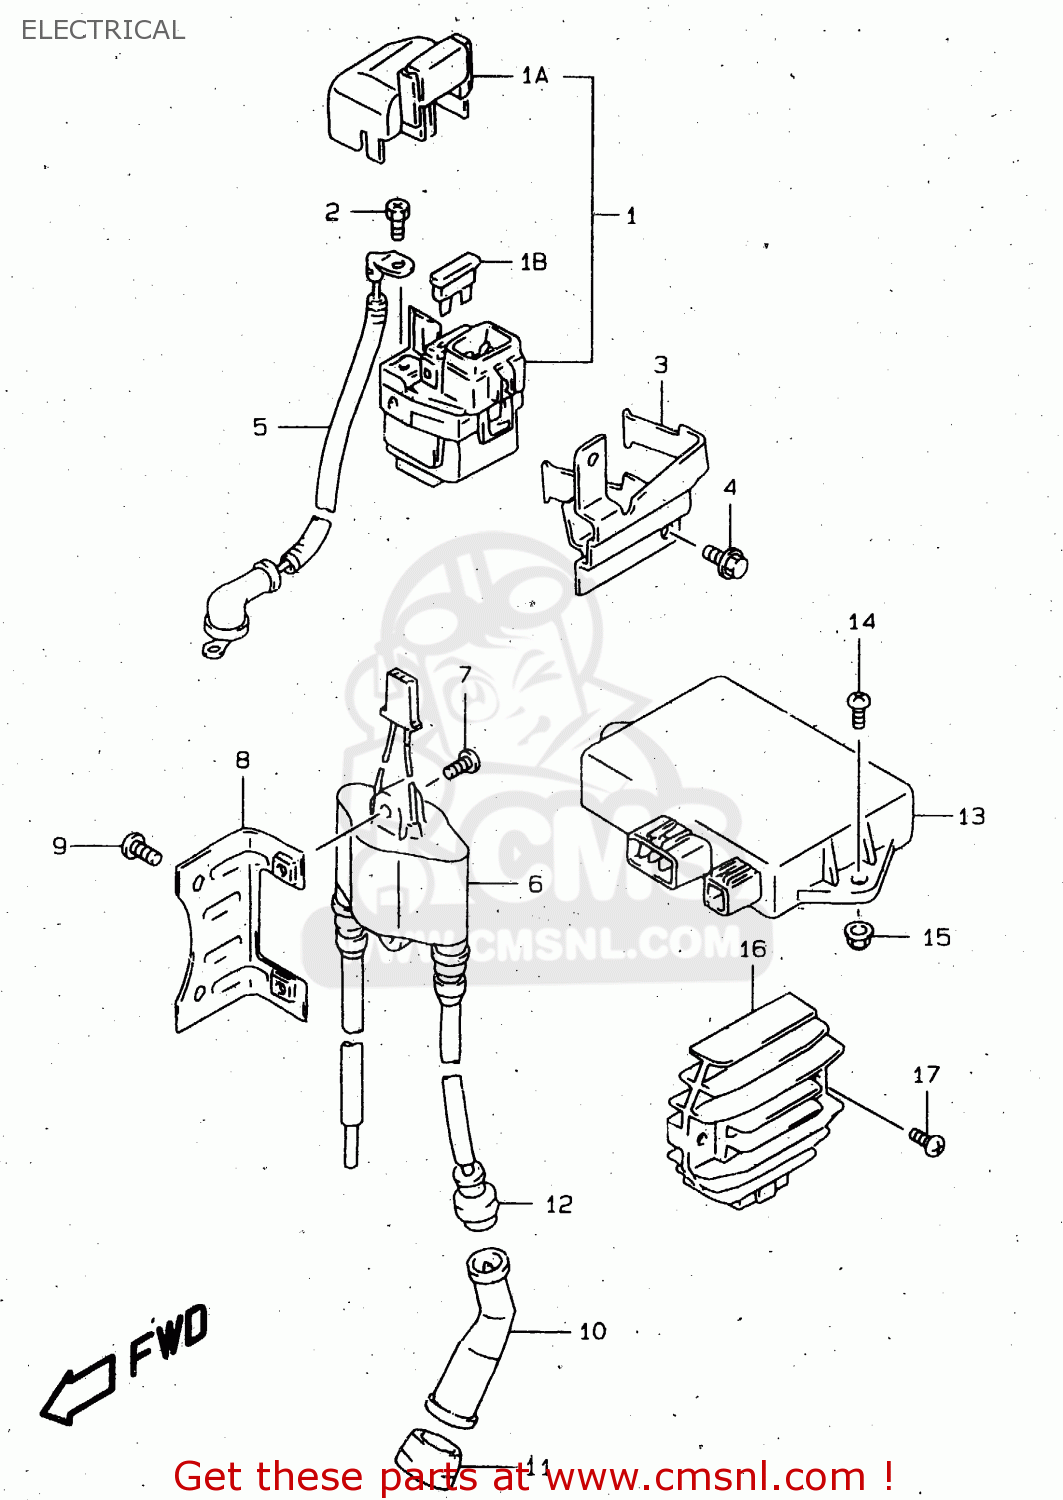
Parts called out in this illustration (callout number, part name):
1	RELAY ASSY,STARTING MOTOR
1A	COVER,STARTER RELAY
1B	FUSE(30A)
2	SCREW(6X8)
3	BRACKET,STARTING MOTOR RELAY
4	BOLT(6X8)
5	WIRE,STARTER MOTOR
6	COIL ASSY,IGNITION
7	SCREW
8	BRACKET,IGNITION COIL
9	SCREW 6X10
10	CAP,SPARK PLUG
11	SEAL,SPARK PLUG
12	SEAL,HIGH TENSION CORD
13	CDI UNIT
14	SCREW
15	NUT
16	RECTIFIER ASSY
17	SCREW
